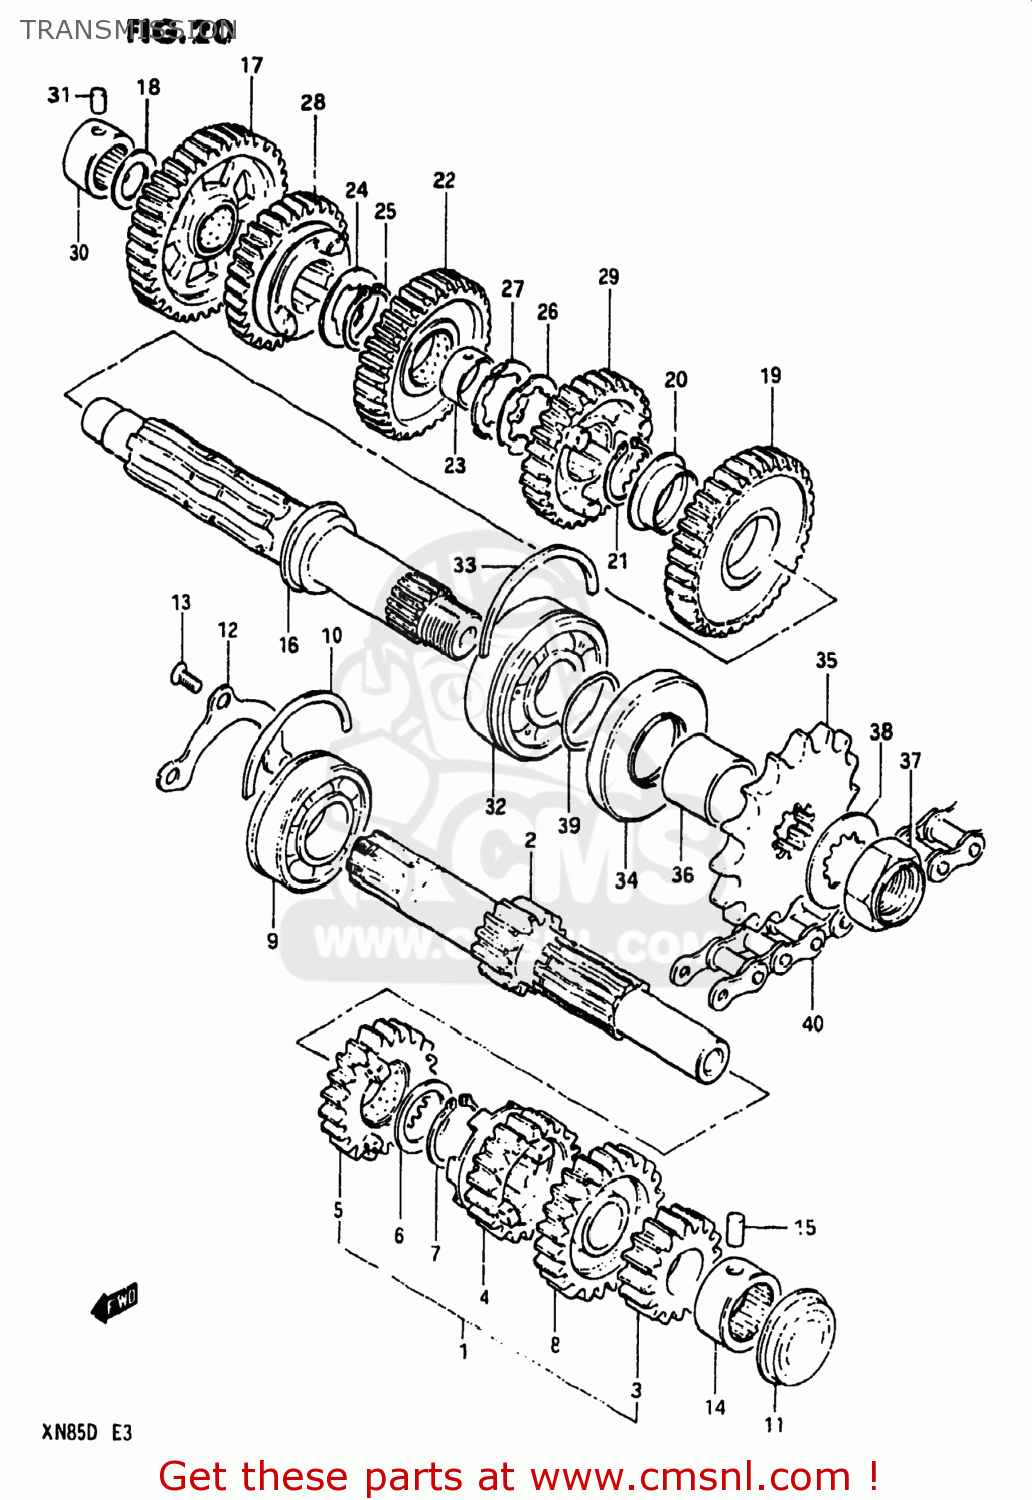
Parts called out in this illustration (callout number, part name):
1	SHAFT,COUNTER
2	SHAFT,COUNTER
3	GEAR,SECOND DRIVE
4	GEAR,THIRD DRIVE
5	GEAR,FOURTH DRIVE
6	WASHER,LOCK
7	CIRCLIP
8	GEAR,FIFTH DRIVE
9	BEARING(25X62X17)
10	C-RING
11	PLUG
12	RETAINER,CNTR SHAFT BEARING
13	SCREW
14	BEARING
15	PIN
16	SHAFT,DRIVE
17	GEAR,FIRST DRIVEN
18	WASHER,THRUST
19	GEAR,SECOND DRIVEN
20	BUSH(28X32X2)
21	CIRCLIP
22	GEAR,THIRD DRIVEN
23	BUSH,3RD DRIVEN GEAR
24	WASHER,LOCK
25	CIRCLIP
26	WASHER,LOCK
27	WASHER
28	GEAR,FOURTH DRIVEN
29	GEAR,FIFTH DRIVEN
30	BEARING(20X34X20)
31	PIN
32	BEARING(25X62X17)
33	C-RING
34	SEAL,OIL(32X62X7)
35	SPROCKET,ENGINE(NT:16)
36	SPACER
37	NUT
38	WASHER
39	O RING(D:1,ID:24.5)
40	CHAIN ASSEMBLY,DRIVE
